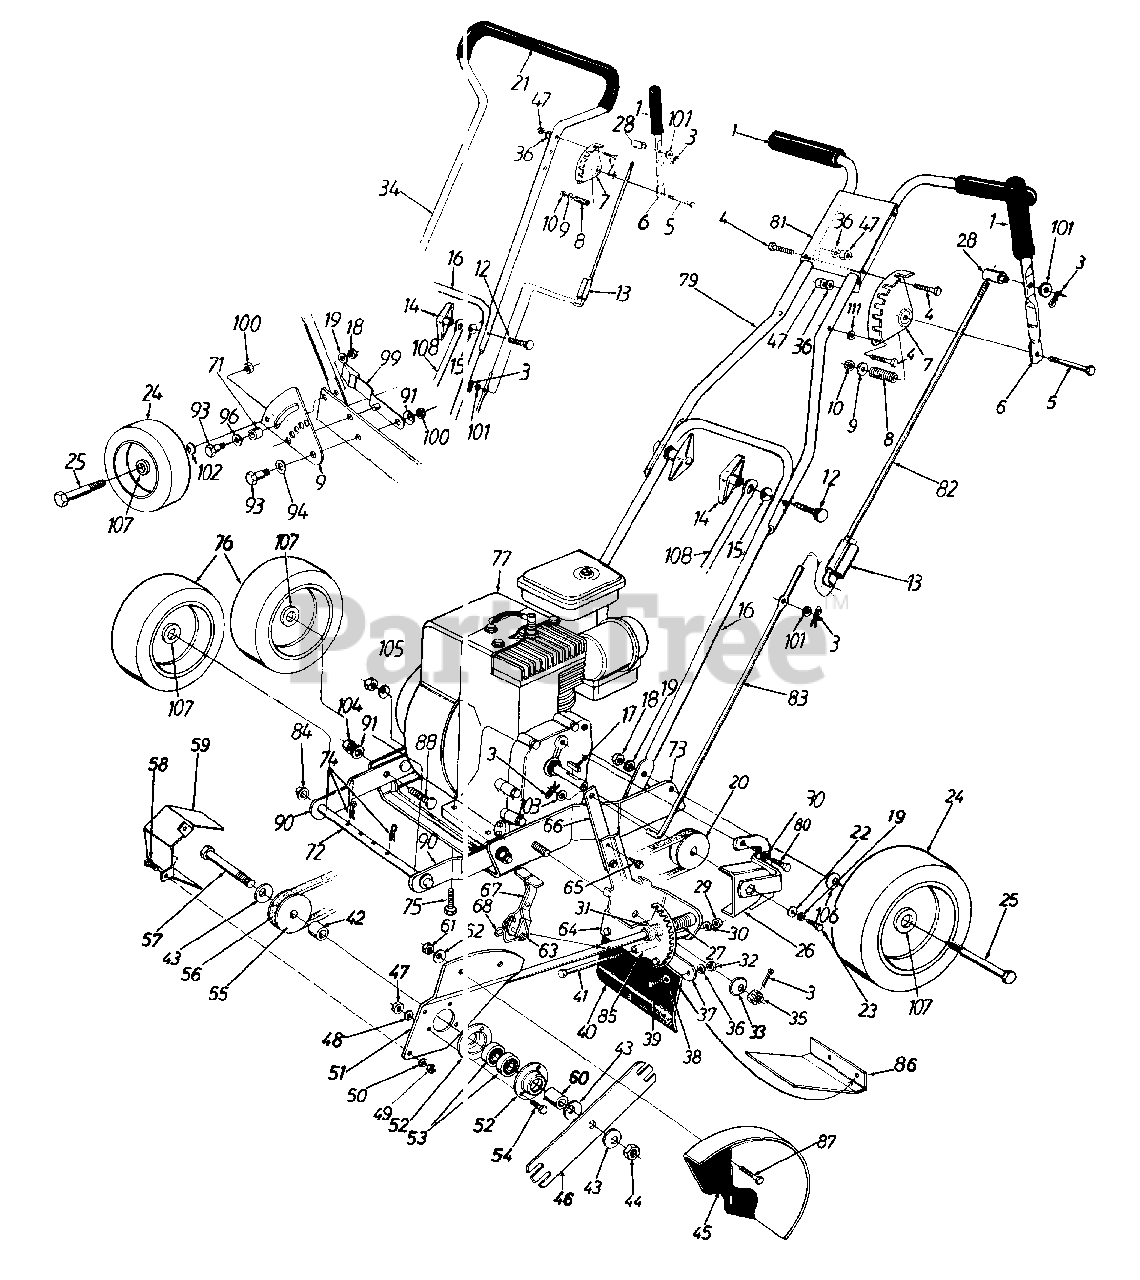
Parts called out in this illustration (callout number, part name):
1	Foam Grip
3	Cotter Pin 5/16" Dia.
4	Hex Bolt 1/4-20 x 1.25" Lg.
5	Hex Bolt 5/16-18 x 2" Lg.
8	Compression Spring 1.38" Lg.
9	Fl-Wash. .344" I.D.
10	Hex L-Nut 5/16-18 Thd.
12	Curv. Hd. Bolt 5/16-18 x 2" Lg.
13	Clutch Rod Lock
14	Wing Nut Ass'y.
15	Saddle Wash. .32" I.D. x .937"
18	Hex Nut 3/8-16 Thd.
19	L-Wash. 3/8" I.D.
20	Engine Pulley
21	Foam Grip
22	Fl-Wash. .385" I.D.
23	Hex Bolt 3/8-24 x 1" Lg.
24	Rear Wheel Ass'y.-Bar Tread
25	Shoulder Bolt .498" Dia.
28	Ferrule
29	Hex Nut 5/16-18 Thd.
30	L-Wash. 5/16" I.D.
31	Spring Pin Spir. 1/4" Dia.
32	Hex Nut 1/4-20 Thd.
33	Bell-Wash. .535" I.D.
34	Upper Loop Handle
35	Hex Slotted Nut 1/2-20 Thd.
36	L-Wash. 1/4" I.D.
39	Hex Bolt 1/4-20 x .62" Lg.
41	Hex Bolt 5/16-18 x 4.5" Lg.
42	Spacer 1.030" Lg.
43	Bell-Washer. .63" I.D.
44	Hex Jam L-Nut 5/8-18 Thd.
47	Hex Nut 1/4-20 Thd.
48	L-Wash. 1/4" I.D.
49	Hex Nut 1/4-20 Thd.
50	L-Wash. 1/4" I.D.
53	Ball Bearing .62" I.D.
54	Hex Bolt 1/4-20 x .62" Lg.
55	3/8" "V"-Pulley
56	"V"-Belt
57	Hex Bolt 5/8-18 x 4.5" Lg.
58	Hex Bolt 1/4-20 x .625" Lg.
60	Sleeve .90" Lg.
61	Hex Nut 5/16-18 Thd.
62	Bell-Wash. .345" I.D.
63	Spring Pin Spir. 1/4" Dia.
68	Torsion Spring
71	Spacer
72	Axle 8.20" Lg. (Front)
75	Hex TT-Tap Scr. 3/8-16 x 1" Lg.
76	Front Wheel Ass'y.-Bar Tread
77	Engine
83	Lower Clutch Rod
84	Push Cap 1/2" Dia.
85	Spacer 3.765" Lg.
88	Ribbed Neck Bolt 3/8-24 x .8" Lg.
93	Shld. Bolt .5" Dia.
94	Bell-Wash. .515" I.D.
96	Fl-Wash. .51" I.D. x 1.0" O.D.
100	Hex Jam Nut 3/8-16 Thd.
101	Fl-Wash. .344" I.D. x .62" O.D.
102	Wave Wash. .51" I.D.
103	Fl-Wash. .406" I.D. x .81" O.D.
104	Hex Nut 3/8-24 Thd.
105	Bell-Wash. .396" I.D. x 1.14" O.D.
106	Bell-Wash. .38" I.D. x .88" O.D.
107	Ball Bearing
